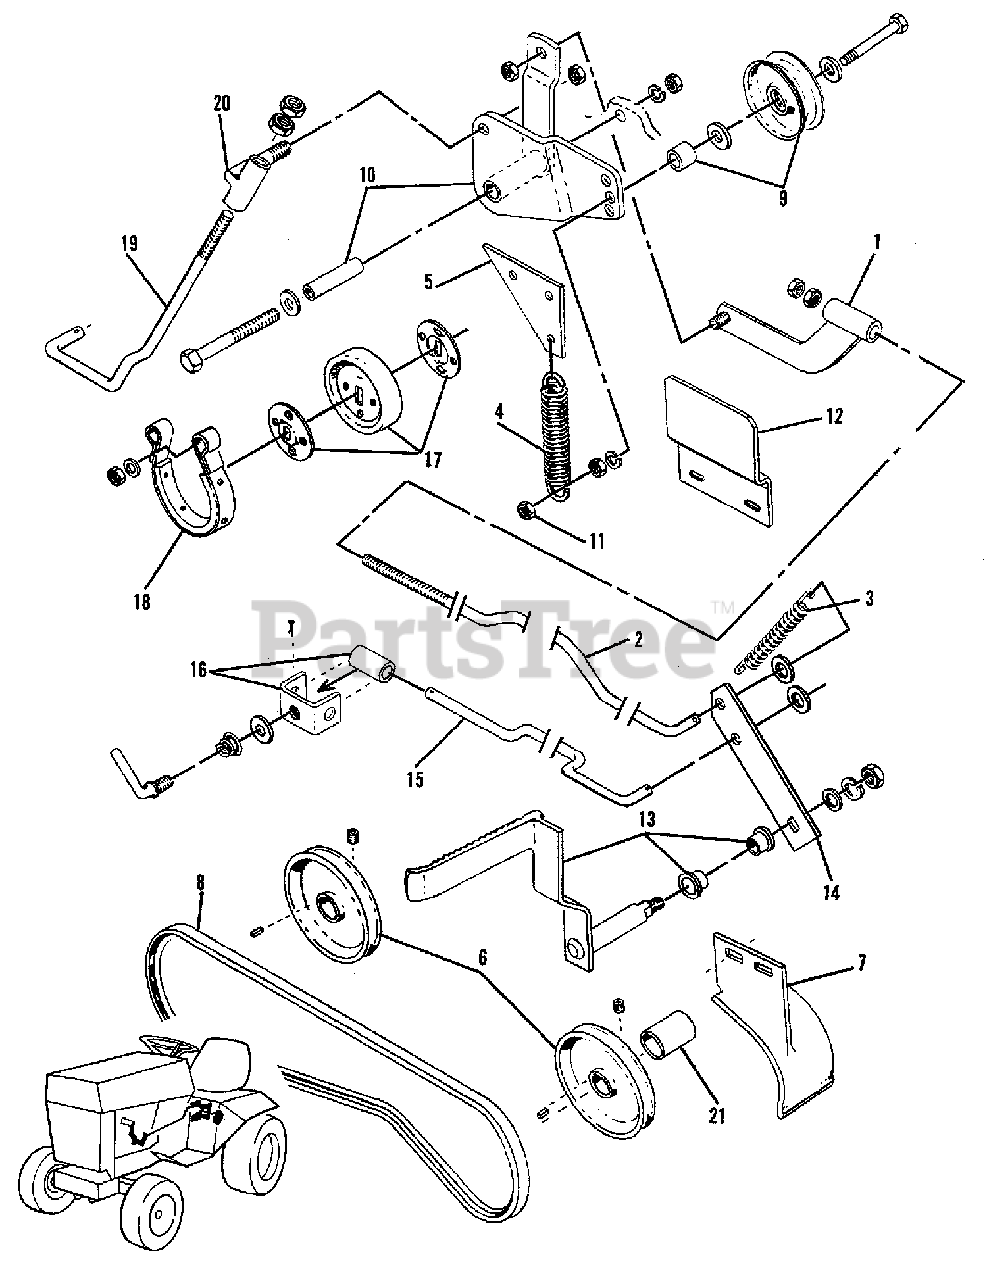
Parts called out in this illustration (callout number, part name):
1	GUIDE ASSEMBLY, Rod
1	NUT, Lock, 5/16NC
2	ROD, Clutch and Brake
2	NUT, 5/16NC
2	WASHER, 5/16
3	TENSION SPRING, Clutch
4	SPRING, Idler Pulley
5	BRACKET, Spring
5	CAPSCREW, 5/16 NC x 5/8
5	LOCKWASHER, 5/16
5	NUT, 5/16NC
6	*PULLEY, Half
6	*KEY
6	*SETSCREW
7	GUARD, Belt
7	BOLT, 5/16NC x 1
7	LOCKWASHER, 5/16
7	WASHER, 5/16
7	NUT, 5/16NC
8	*
9	PULLEY, Idler
9	WASHER, 3/8
9	CAPSCREW, 3/8NC x 2-1/4
9	LOCKWASHER, 3/8
9	NUT, 3/8NC
10	LEVER ASSEMBLY, Idler
10	WASHER, 7/16
10	CAPSCREW, 7/16NC x 3-3/4
10	LOCKWASHER, 7/16
10	NUT, 7/16NC
11	NUT, Lock, 3/8 NC
12	PLATE, Guide
13	PEDAL ASSEMBLY, Foot
13	BUSHING, Flange
13	WASHER, 3/8
13	LOCKWASHER, 3/8
13	NUT, 3/8NC
14	ARM, Foot Pedal
15	ROD, Parking Brake
15	PIN, Cotter, 1/8 x 3/4
15	WASHER, 5/16
15	PIN, Cotter, 3/32 x 3/4
16	BRACKET ASSEMBLY, Parking Brake
16	LOCK, Parking brake
16	WASHER, 7/16
16	SPRING, Idler Pulley
17	DRUM, Brake
17	WASHER, Special
17	WASHER, 7/16
17	NUT, Lock, 7/16NC
18	BAND ASSEMBLY, Brake
18	WASHER, 3/8
18	LOCKWASHER, 3/8
18	CAPSCREW, 3/8NC x 1-3/4
19	ROD, Brake
19	NUT, 3/8NC
19	PIN, Cotter, 3/32 x 3/4
20	GUIDE ASSEMBLY, Rod
20	NUT, Lock, 5/16NC
21	*
22	CAPSCREW, 7/16NC x 1
22	LOCKWASHER, 7/16
